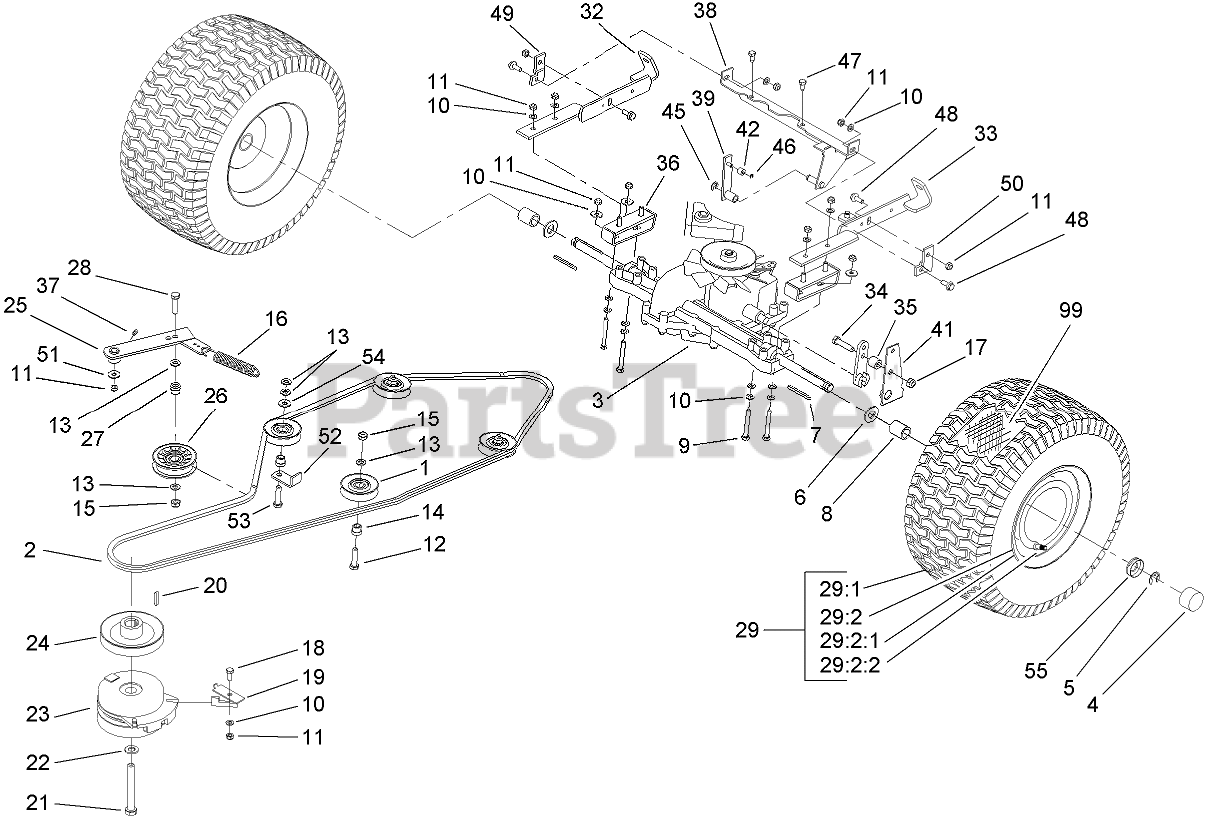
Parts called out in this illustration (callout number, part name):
1	PULLEY-IDLER
2	V-BELT-TRACTION
3	TRANSMISSION
4	CAP-HUB
5	CLIP-SPRING
6	WASHER
7	KEY-SQUARE
8	SPACER-AXLE
9	SCREW-HH
10	WASHER-PLAIN
11	NUT-LOCK, NI
12	SCREW-HH
13	WASHER-FLAT
14	BUSHING-IDLER
15	NUT-LOCK, NI
16	SPRING
17	NUT-LOCK, NI
18	SCREW-HH
19	RETAINER
20	KEY-SQUARE
21	SCREW-HH
22	WASHER-SPRING, BELLEVILLE
23	CLUTCH-ELECTRIC
24	PULLEY-ENGINE
25	ARM-IDLER
26	PULLEY-IDLER
27	BUSHING-IDLER
28	SCREW-HH
29	WHEEL AND TIRE ASM
29:1	TIRE
29:2	WHEEL ASM
29:2:2	Valve-Tire
32	Bracket-Right
33	Bracket-Left
34	SCREW-HH
35	SLEEVE
36	BRACKET-SUPPORT
37	FITTING-GREASE
38	Bar ASM
39	Arm-Switch
42	Roller
45	Stirrup
46	STIRRUP
47	SCREW-THREAD FORMING
48	SCREW-HEX
49	BRACKET-RIGHT
50	BRACKET-LEFT
51	WASHER-PLAIN
52	RETAINER-BELT
53	SCREW-HH
54	WASHER-FLAT
55	RETAINER-CAP, HUB
